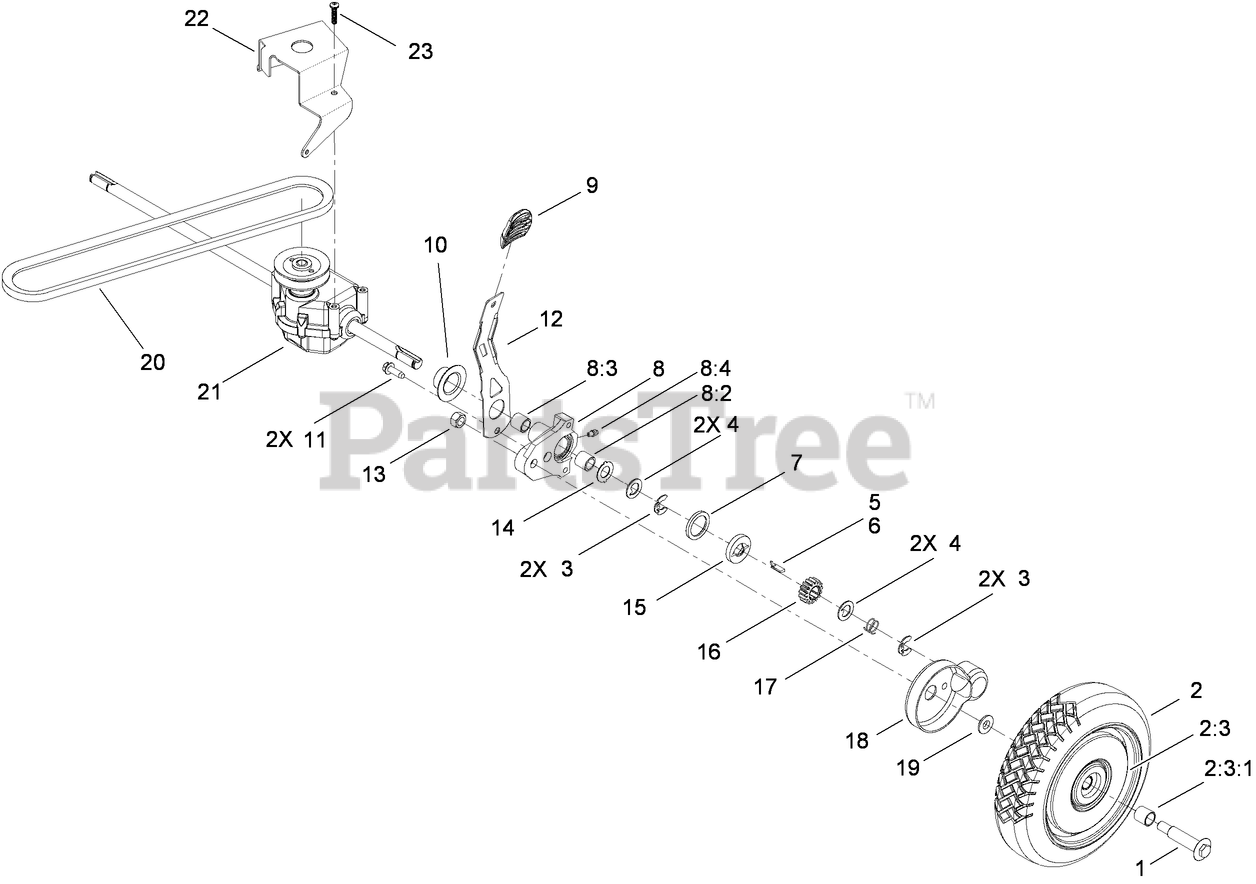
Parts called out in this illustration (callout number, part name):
1	BOLT-SHOULDER
2	WHEEL AND TIRE ASM
2:3	Loose Parts Package
2:3:1	BUSHING
3	RING-RETAINING,CLIP
4	WASHER-THRUST, KEYED
5	KEY-ROCKING, RH
6	KEY-ROCKING, LH
7	RING-FRICTION
8	PIVOT ARM ASM
8:2	BUSHING
8:3	BUSHING
8:4	FITTING-GREASE
9	KNOB-LEVER, HOC
10	CAP-END
11	SCREW-HWHTF
12	ARM-SPRING
13	LOCKNUT
14	WASHER-ARM, PIVOT
15	WASHER-CLUTCH
16	GEAR-PINION
17	SPRING-COMPRESSION
18	COVER-WHEEL
19	SPACER-COVER, WHEEL
20	V-BELT
22	BRACKET-TRANSMISSION
23	SCREW-PLASTITE
